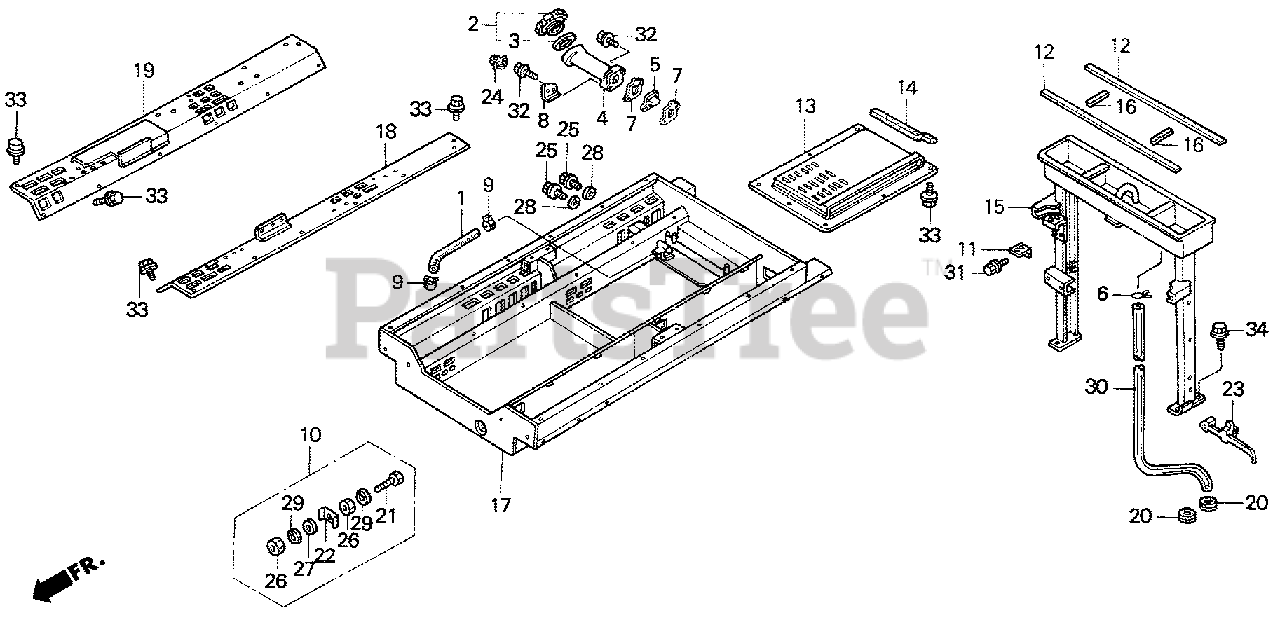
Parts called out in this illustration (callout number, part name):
1	TUBE, OIL DRAIN
2	CAP ASSY., OIL FILLER
3	GASKET, OIL FILLER
5	GUIDE, OIL
6	CLIP, BREATHER TUBE
7	GASKET, RACK COVER (NOT AVAILABLE)
7	GASKET, RACK COVER (NON-ASBESTOS)
8	BRACKET, FUEL TUBE
9	CLAMP B, WATER HOSE
10	TERMINAL SET, GROUND
11	BRACKET, MAIN FUSE
12	SEAL, COVER (UPPER)
13	COVER, OIL PAN MAINTENANCE *NH105* (MAT BLACK)
14	OIL SEAL, PAN MAINTENANCE COVER
15	BEAM, CENTER *B132* (JOHN BLUE)
16	SEAL, CENTER BEAM (B)
17	COVER (LOWER) *NH105* (MAT BLACK)
18	PLATE, R. (LOWER) *NH105* (MAT BLACK)
19	PLATE, L. (LOWER) *NH105* (MAT BLACK)
20	GROMMET, FENDER
21	BOLT, HEX. (6X28)
22	RETAINER (6MM)
23	BAND, WIRE HARNESS (WHITE)
24	CLIP, WIRE HARNESS
25	BOLT, DRAIN PLUG (12MM)
26	NUT, HEX. (6MM)
27	WASHER, PLAIN (6MM)
28	WASHER, DRAIN PLUG (12MM)
29	WASHER, SPRING (6MM)
30	BULK HOSE, VINYL (12X16X3000) (12X16X690)
31	BOLT, FLANGE (6X12)
32	BOLT, FLANGE (6X25)
33	BOLT, FLANGE (8X16)
34	BOLT, FLANGE (12X20)
